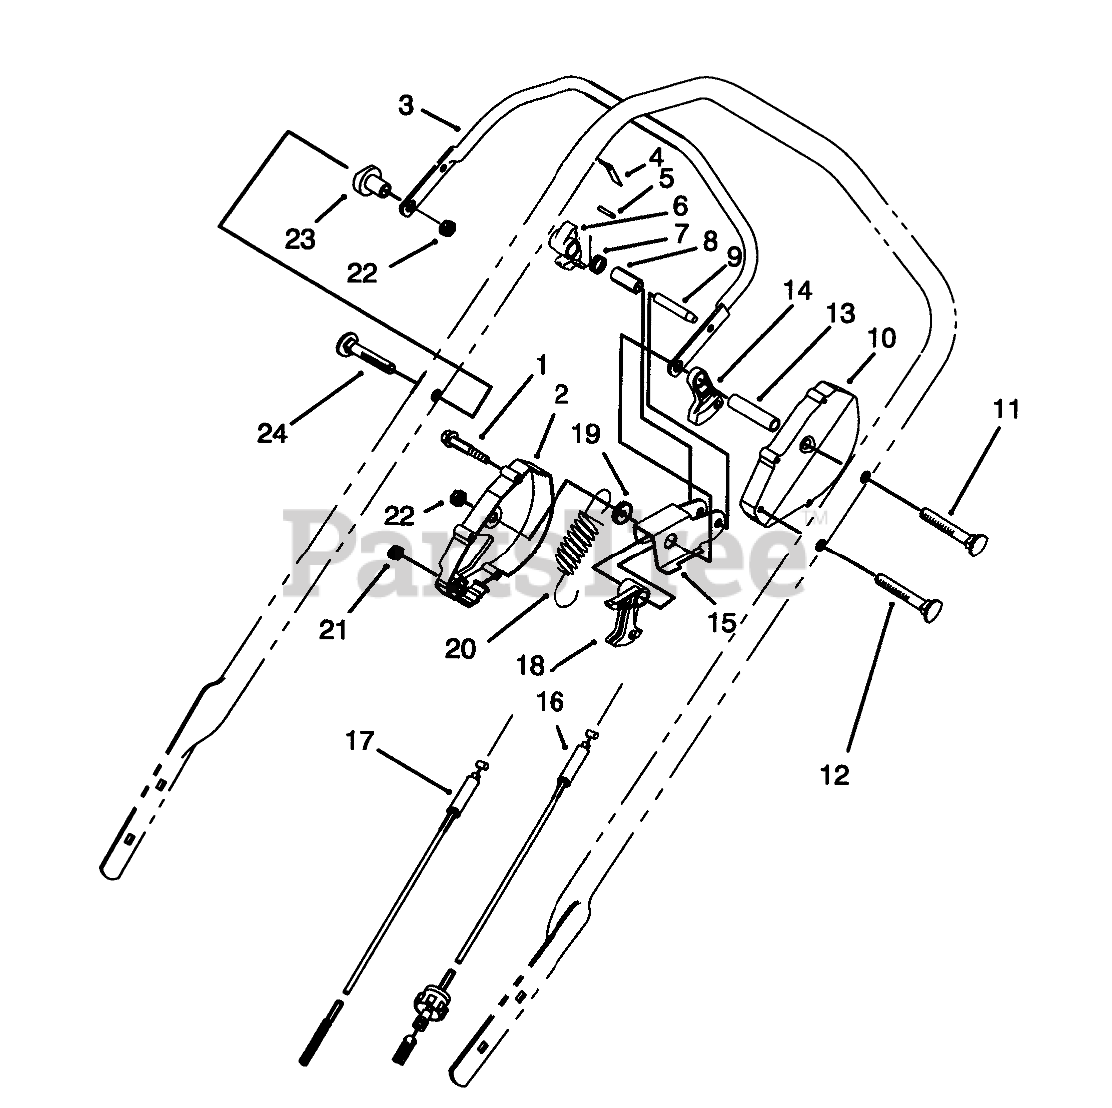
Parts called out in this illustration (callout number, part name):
1	SCREW-HWHTF
2	Housing-Control R.H. (Incl Ref. #4 & 5)
3	Bar-Control
4	SPRING-LEAF
5	PIN-INSERT
6	HOOK-CONTROL
7	SPRING-TORSION
8	SPACER
9	PIN-ROLL, SLOTTED
10	HOUSING-CONTROL, LH
11	OBS MATERIAL EXCEPT FOR SERVICE
12	SCREW-HANDLE
13	TUBING-SPACER
14	LEVER-TRACTION
15	ROCKER
16	TRACTION CABLE
17	CLUTCH CABLE
18	LEVER-CABLE
19	WASHER-NYLON
20	SPRING-DETENT
21	NUT-LOCK NI
22	NUT-LOCK NI
23	SPACER-SUPPORT
24	SCREW-HANDLE
